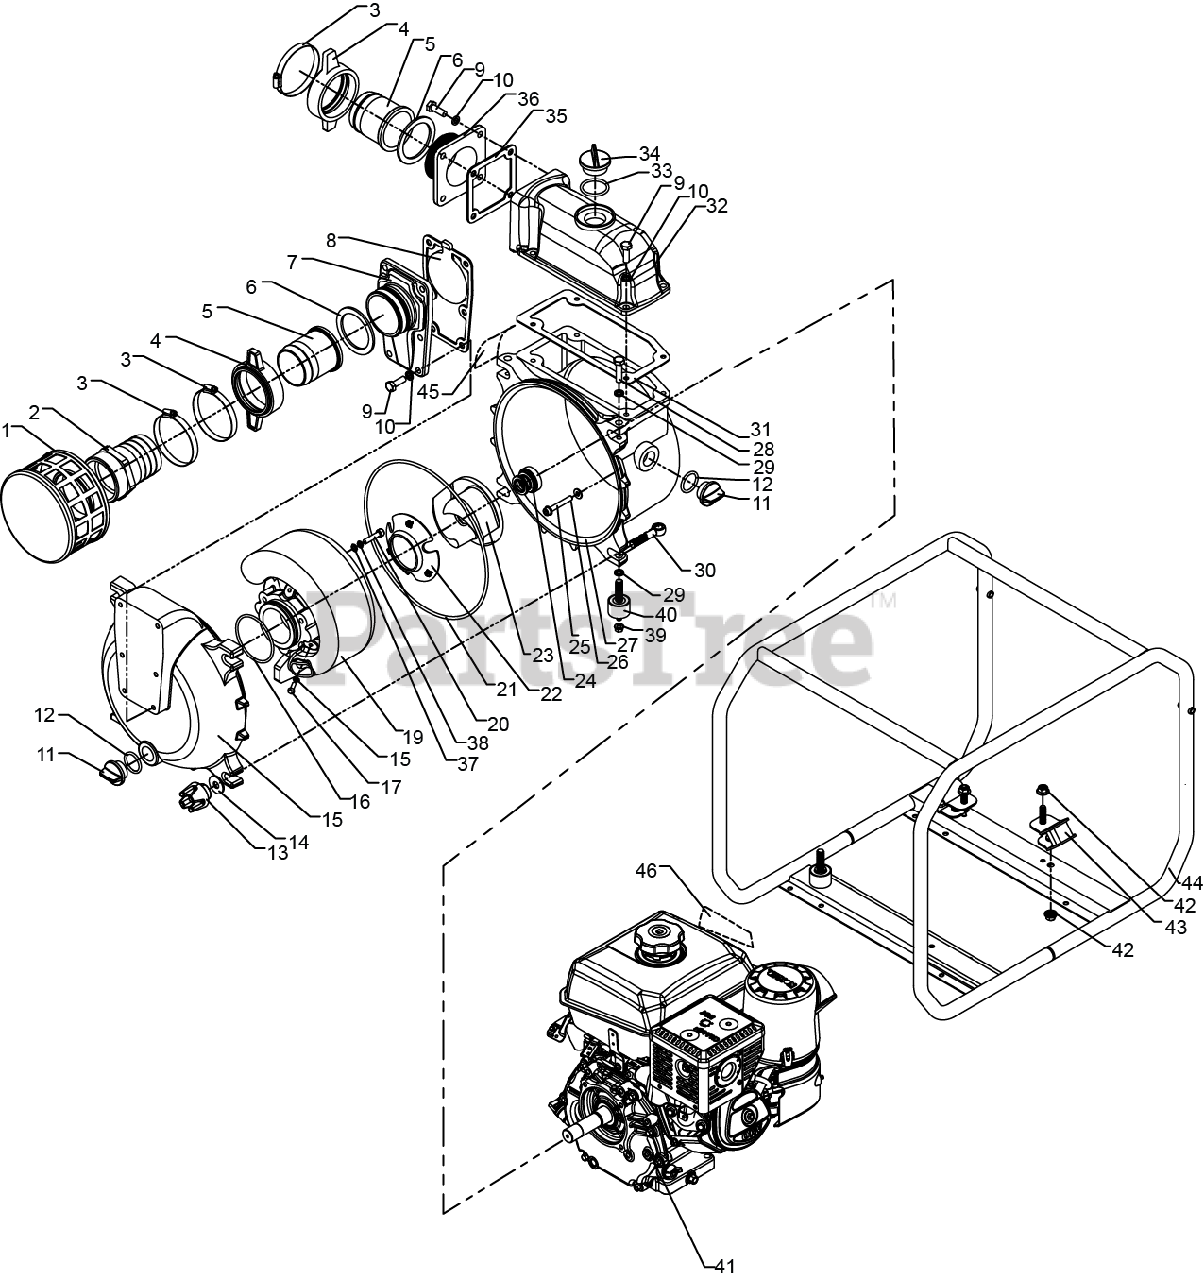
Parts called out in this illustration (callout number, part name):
1	FILTER, STRAINER
2	FITTING, HOSE
4	NUT, COUPLER
5	FITTING, HOSE
7	FLANGE, SUCTION
8	VALVE, CHECK
9	BOLT, M10X30
10	WASHER, LOCK
11	DRAIN PLUG
15	COVER, PUMP
17	BOLT, M6X16
18	WASHER, LOCK
20	BOLT, M8X35
22	COVER, IMPELLER
23	PUMP ASSEMBLY, IMPELLER
24	SEAL, MECHANICAL
25	BOLT, 5/16-24
26	WASHER, ALUMINUM
27	BODY, PUMP CASE
28	BOLT, M12X45
29	WASHER, LOCK
30	BOLT, EYE
31	GASKET, RUBBER
32	CHAMBER, DISCHARGE
34	PLUG, PRIMING
35	GASKET, RUBBER
36	FLANGE, DISCHARGE
37	WASHER, LOCK
38	WASHER, LOCK
40	MOUNT, RUBBER FOOT
41	CH395 E3 Engine Parts
43	MOUNT, ENGINE ISO
44	FRAME ASSEMBLY
